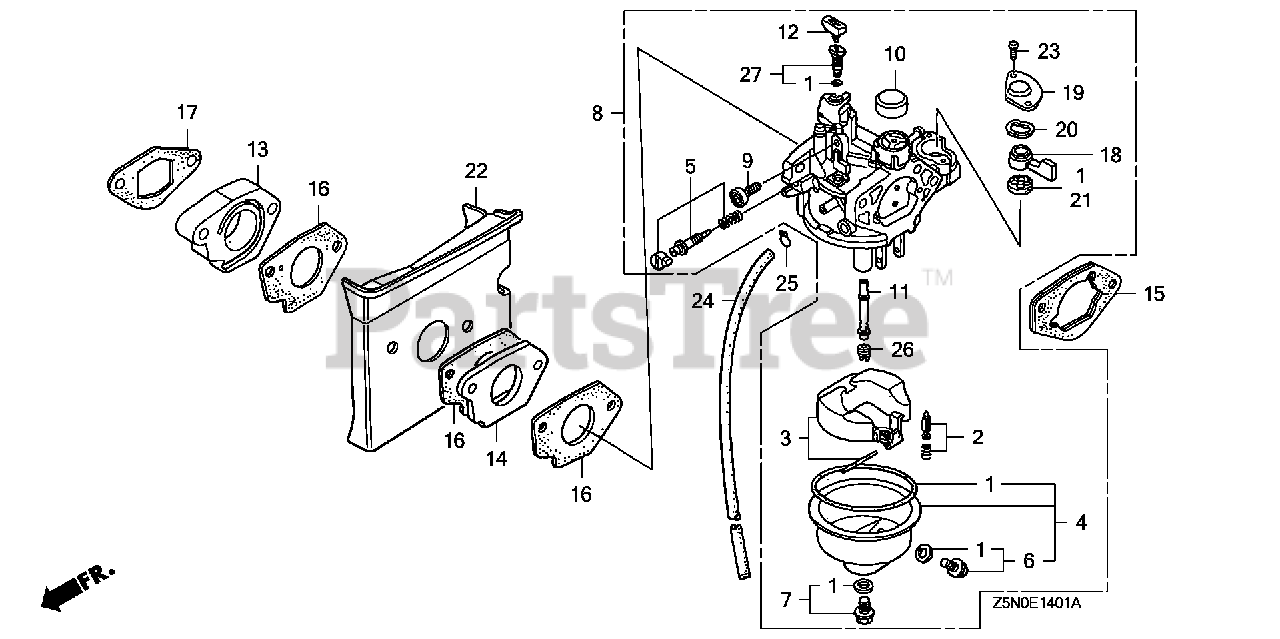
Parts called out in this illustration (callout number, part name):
1	GASKET SET (EXCEPT 16173-001-004)
2	VALVE SET, FLOAT
4	CHAMBER SET, FLOAT
5	SCREW SET, PILOT
6	SCREW SET, DRAIN
7	SCREW SET
8	CARBURETOR ASSY. (BE81B C)
8	CARBURETOR ASSY. (BE81B D)
9	SCREW, THROTTLE STOP
10	CAP, CHOKE DUST
12	COLLAR, SETTING
13	INSULATOR, CARBURETOR
14	INSULATOR, CARBURETOR
15	SPACER, CARBURETOR
16	GASKET, CARBURETOR
17	GASKET, INSULATOR
18	LEVER, PETCOCK
19	PLATE, LEVER SETTING
20	SPRING, PETCOCK LEVER
21	GASKET, PETCOCK
22	GUIDE, AIR
23	SCREW, PAN (3X6)
24	BULK HOSE, FUEL (4.5X1000) (4.5X180)
25	CLIP, TUBE (B8)
26	JET, MAIN (#88)
26	JET, MAIN (#90)
26	JET, MAIN (#92)
27	JET SET, PILOT (#38)
